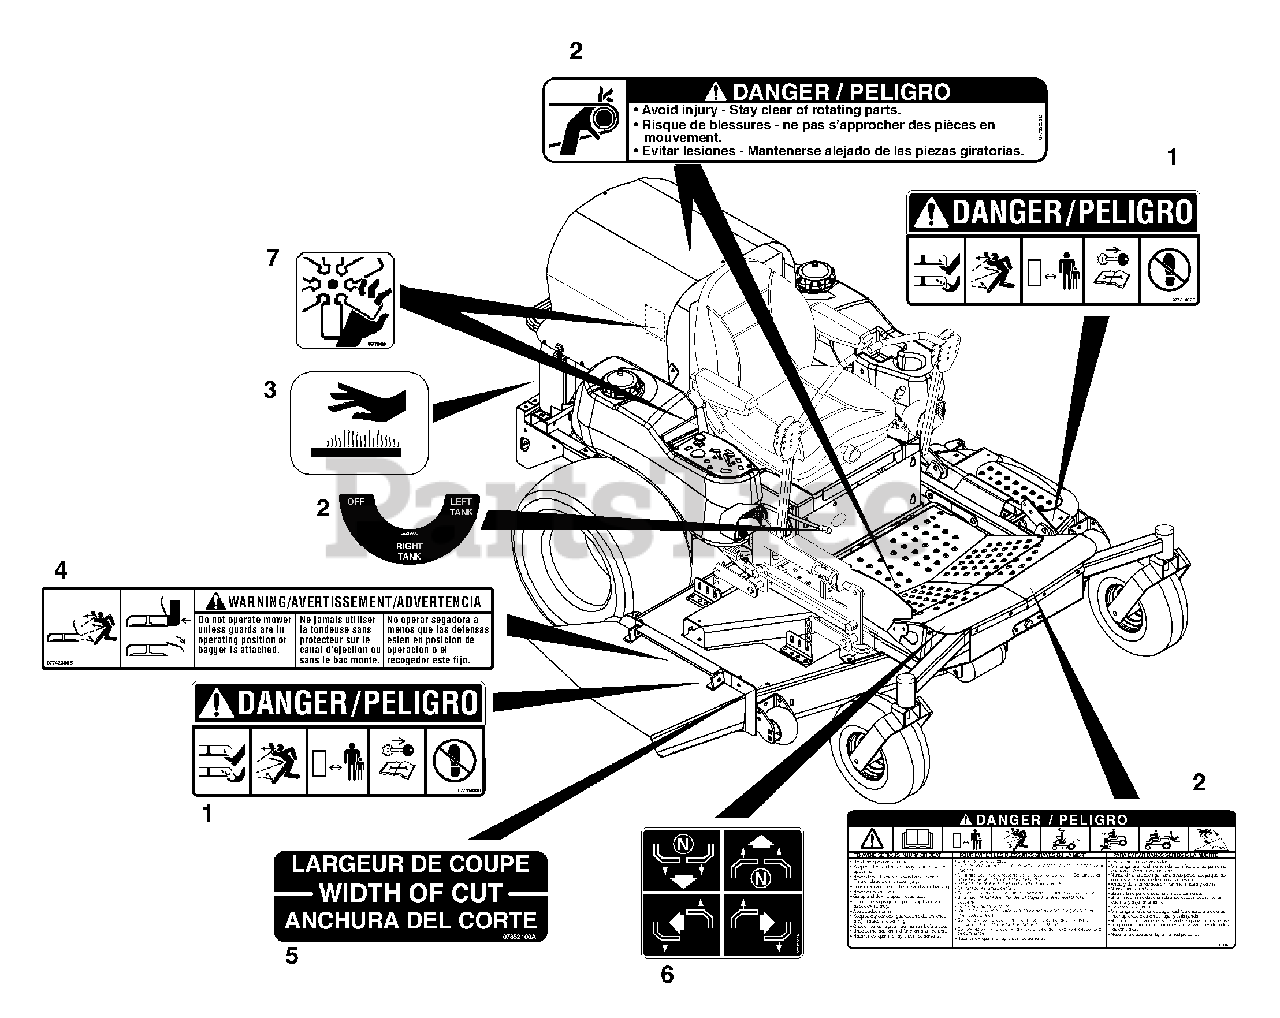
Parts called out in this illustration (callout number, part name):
1	DECAL, MOWER PAN DANGER
2	SET, DECAL-COMMON DANGER/FUEL
3	DECAL, HOT SURFACE
4	DECAL, WARNING
5	WIDTH OF CUT DECAL
6	DECAL, INSTRUCTIONAL-STEERING
7	DECAL, DANGER FAN
